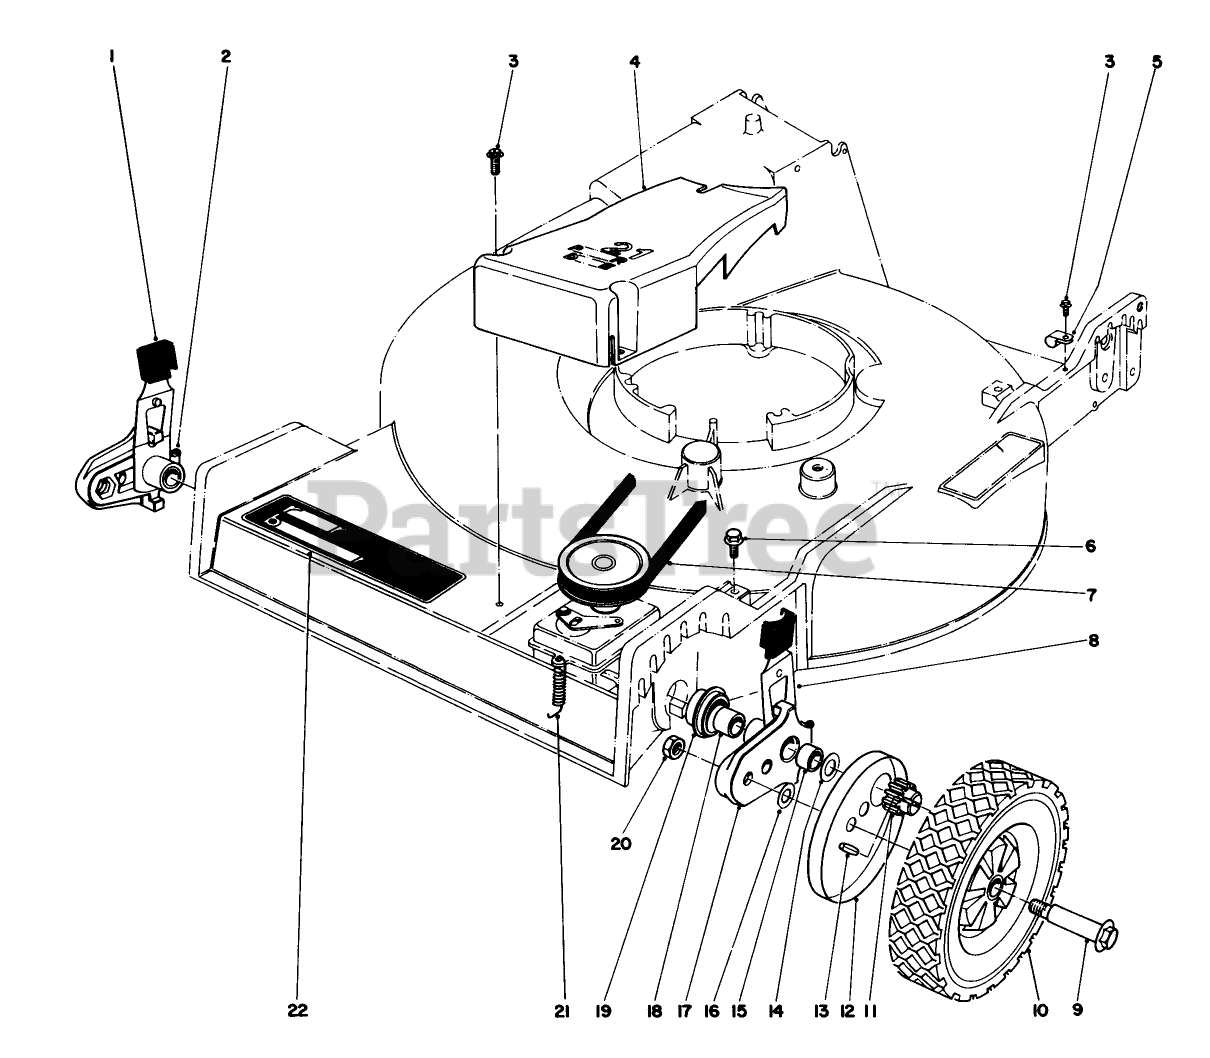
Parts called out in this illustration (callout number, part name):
1	KNOB-ARM
2	FITTING-GREASE
3	SCREW
5	CLAMP-NYLON
6	SCREW-THD ROLL, HWH
7	BELT-V
9	BOLT-WHEEL
14	WASHER-THRUST
15	Bushing
16	WASHER
17	PIVOT ARM ASM
19	END CAP
21	Spring-Tension
